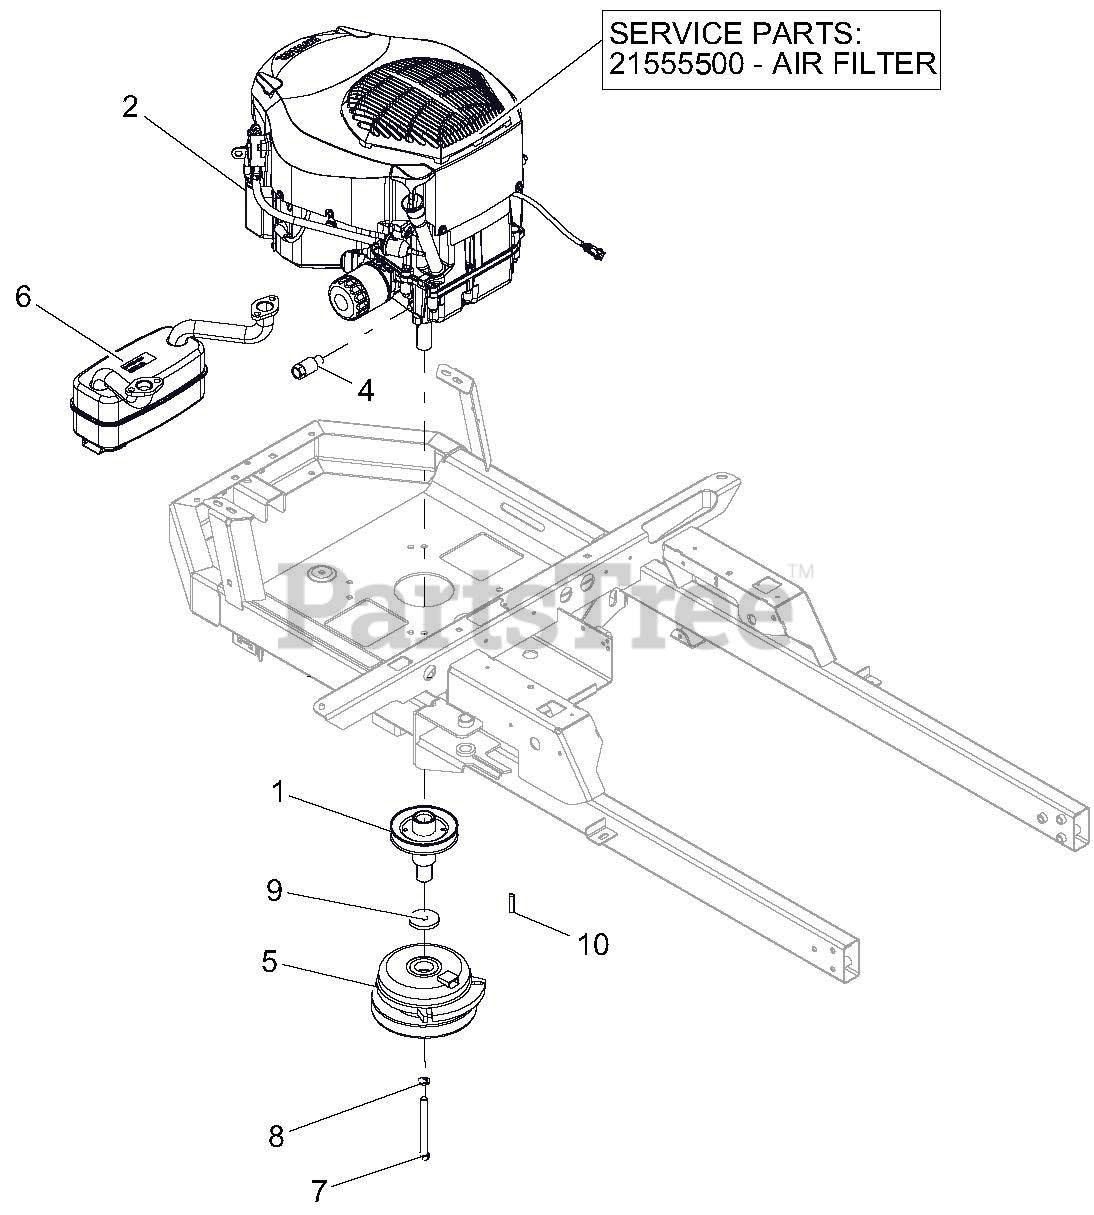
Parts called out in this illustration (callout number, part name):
1	WLDMT, DRIVE SHEAVE
2	ENGINE, KOHLER 22HP TWIN
2	AIR CLEANER, KOHLER
4	DRAIN, OIL
5	CLUTCH,105FTLB MONOPOLE 6.83"
6	MUFFLER, KOHLER TWIN
7	BLT-HEX .44-20X4.50 GR8 YWZC
8	@WSHR-LK .44X.109 REG YWZC
9	WSHR-FL-STL .469X2.00X.25 YWZC
10	KEY-SQ .25 X 1.25 X .25 SAE
